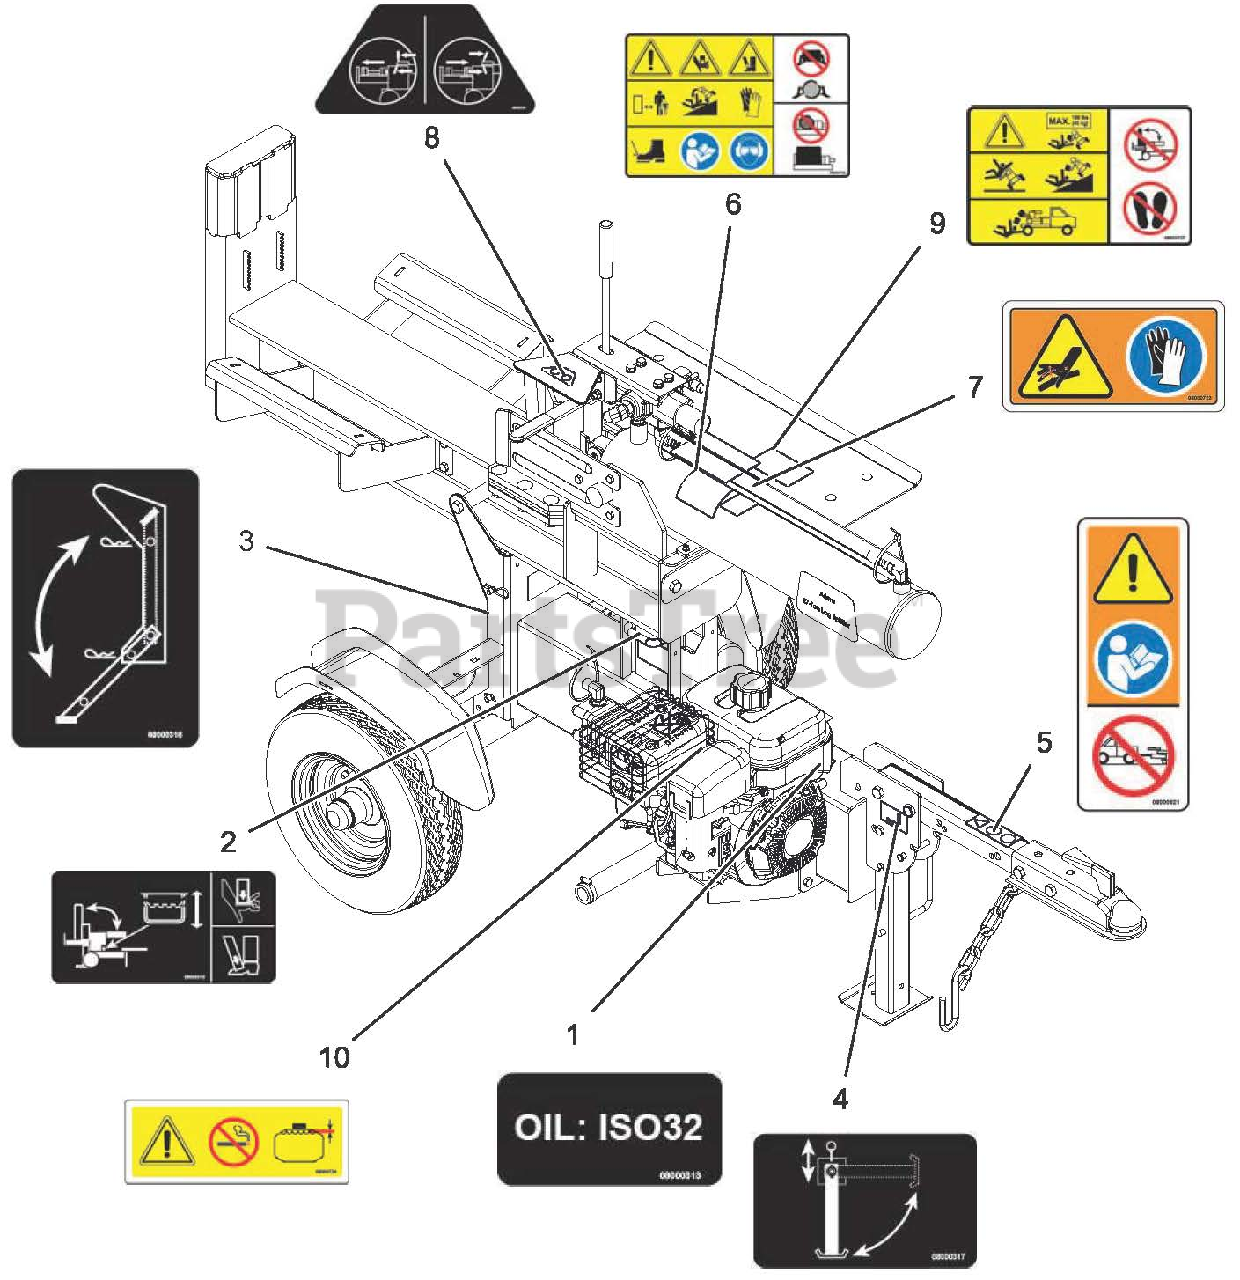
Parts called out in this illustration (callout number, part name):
1	DECAL, LOG SPLITTER HYDRAULIC OIL
2	DECAL, LOG SPLITTER TILT OPERATION
3	DECAL, LOG SPLITTER REAR STAND
4	DECAL, LOG SPLITTER FRONT STAND
5	DECAL, TOWING
6	DECAL, DANGER LOG SPLITTER
7	DECAL, HYD WARNING
8	DECAL, RAM OPERATION
9	DECAL, SPLITTER TABLE
10	DECAL, FUEL WARNING
